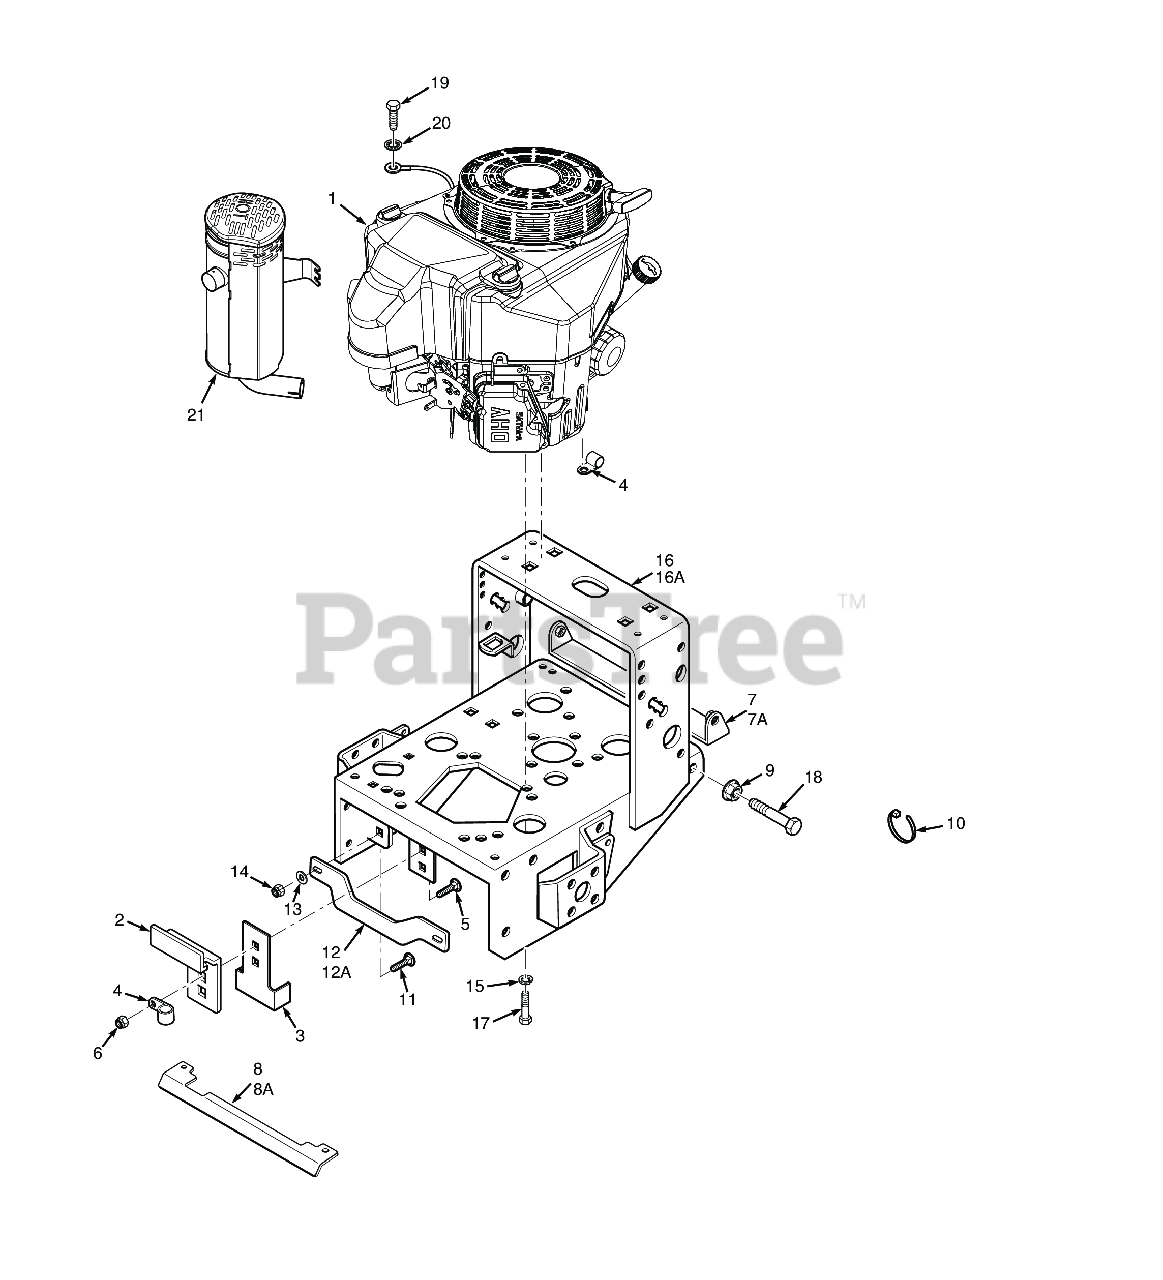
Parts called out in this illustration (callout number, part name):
1	Engine, Kawasaki 14FS (FS481V)
1	Engine, Kawasaki 15FS (FS541V)
1	Engine, Kawasaki FS600V (Recoil Start)
2	Plate, Clutch Bracket
3	Plate, Clutch Anti-Rotation
4	Clamp, Cable 1/2" I.D.
5	Bolt, Carriage 5/16-18x1" (large frame units only)
6	HEX NUT, ELASTIC STOP LOCK, 5/16-18
7	Pulley Guard, 16" Small Frame
7A	Pulley Guard, 20" Large Frame
8	Heatshield, 16" Small Frame
8A	Heatshield, 20" Large Frame
9	Nut, Serrated Flange 5/16-18 (Right Front Engine Mounting, Briggs and Kohler Only)
10	Cable Tie, .19 x 8.0"
11	SHORT SQ. NECK CARRIAGE BOLT, 3/8-16 X 1-1/4"
12	Brace, (16" Small Frame)
12A	Brace, (20" Large Frame)
13	Flatwasher, 3/8 (.391 x .938 x .105 HD) Grade 8
14	HEX NUT, ELASTIC STOP LOCK, 3/8-16
15	Lockwasher, 3/8" Spring, Kawasaki FX / FS
16	Engine Deck (16" Wide) with Decals - Small Frame
16A	Engine Deck (20" Wide) with Decals - Large Frame
17	Bolt, Hex Head 3/8-16 x 1-1/4", Kawasaki FX / FS
18	Bolt, Hex Head 5/16-18 x 2-1/2" (x3) (35BV & 37BV-EFI)
19	Bolt, Hex Head M8 - 1.25 x 16 (48V / 52V)
20	Lockwasher, 5/16" Ext. Tooth (Kohler x1)
21	Muffler, Kawasaki (FS481, FS541, FS600)
